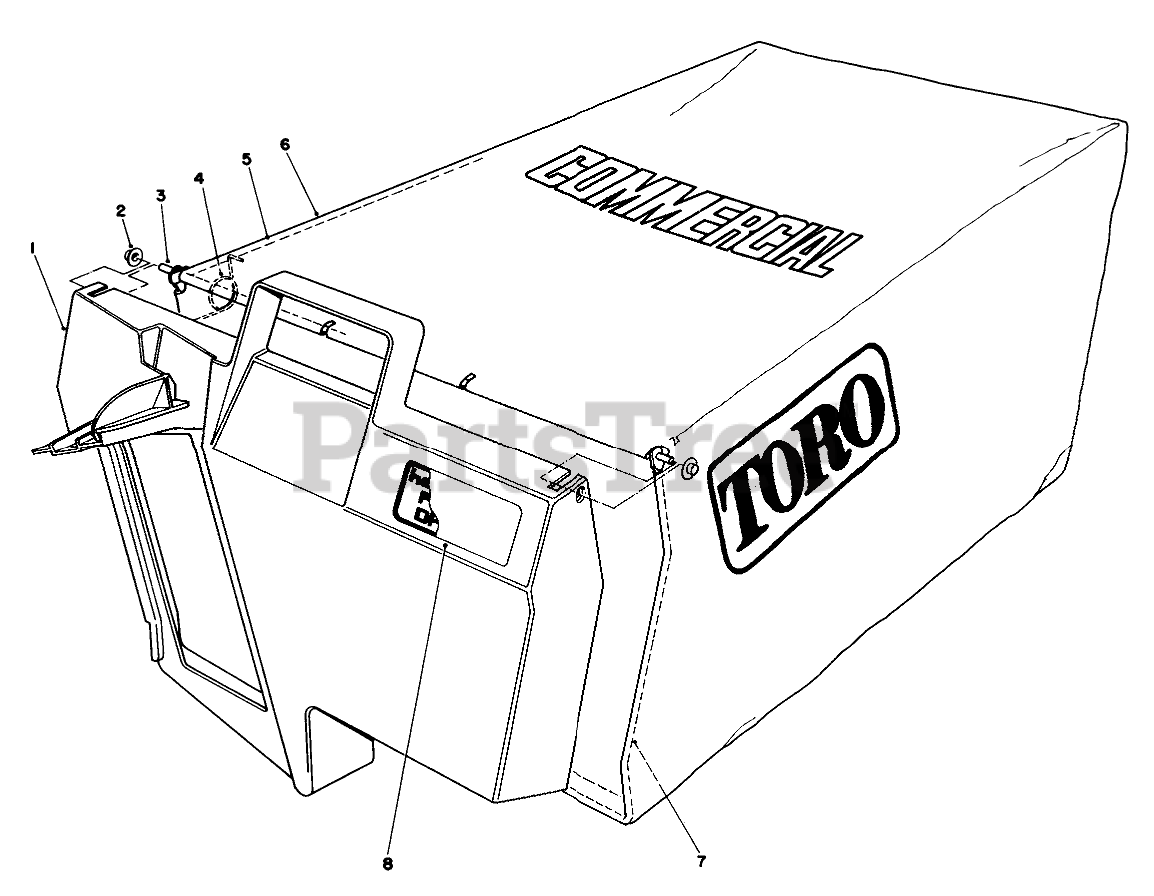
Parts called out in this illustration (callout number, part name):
1	DOOR-BAG, GRASS
2	Plush Knot Cap
3	HINGE-DOOR, BAG
4	SPRING
5	FRAME-BAG, UPPER
6	Bag
7	FRAME-BAG
8	BAG DOOR DECAL
